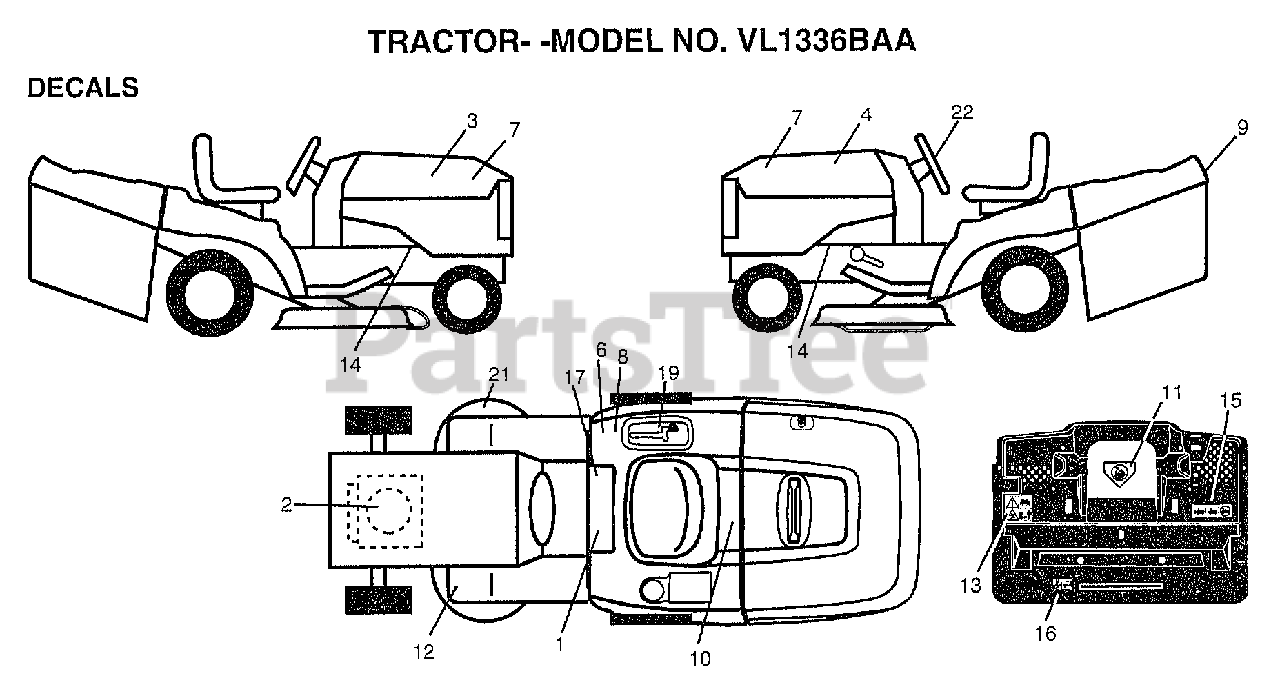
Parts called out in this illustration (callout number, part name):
1	DECAL.READ.O.MANU
2	DECAL, ENGINE
3	DECAL, HOOD
4	DECAL, HOOD
5	DECAL.CONSOLE.6SP.CRD
7	NAMEPLATE HD VERT
8	DECAL.EURO.ST.CE.
9	DECAL.FENDER
10	DECAL.BATRY.3-3908
11	DECAL.DANGER.CUTF
12	DECAL-BRAKE/CLUTC
13	DECAL.WARNING.BACKPLATE.CRD
14	"DECAL CHASSIS,HOT"
15	DECAL, OPER BAG
16	DECAL.DRAWBAR.LDL
17	DECAL BRAK PARK
19	DECAL.CONSOLE.6SP.CRD
21	DECAL.DECK.HEX.BELT
22	DECAL.WHL.STRG
